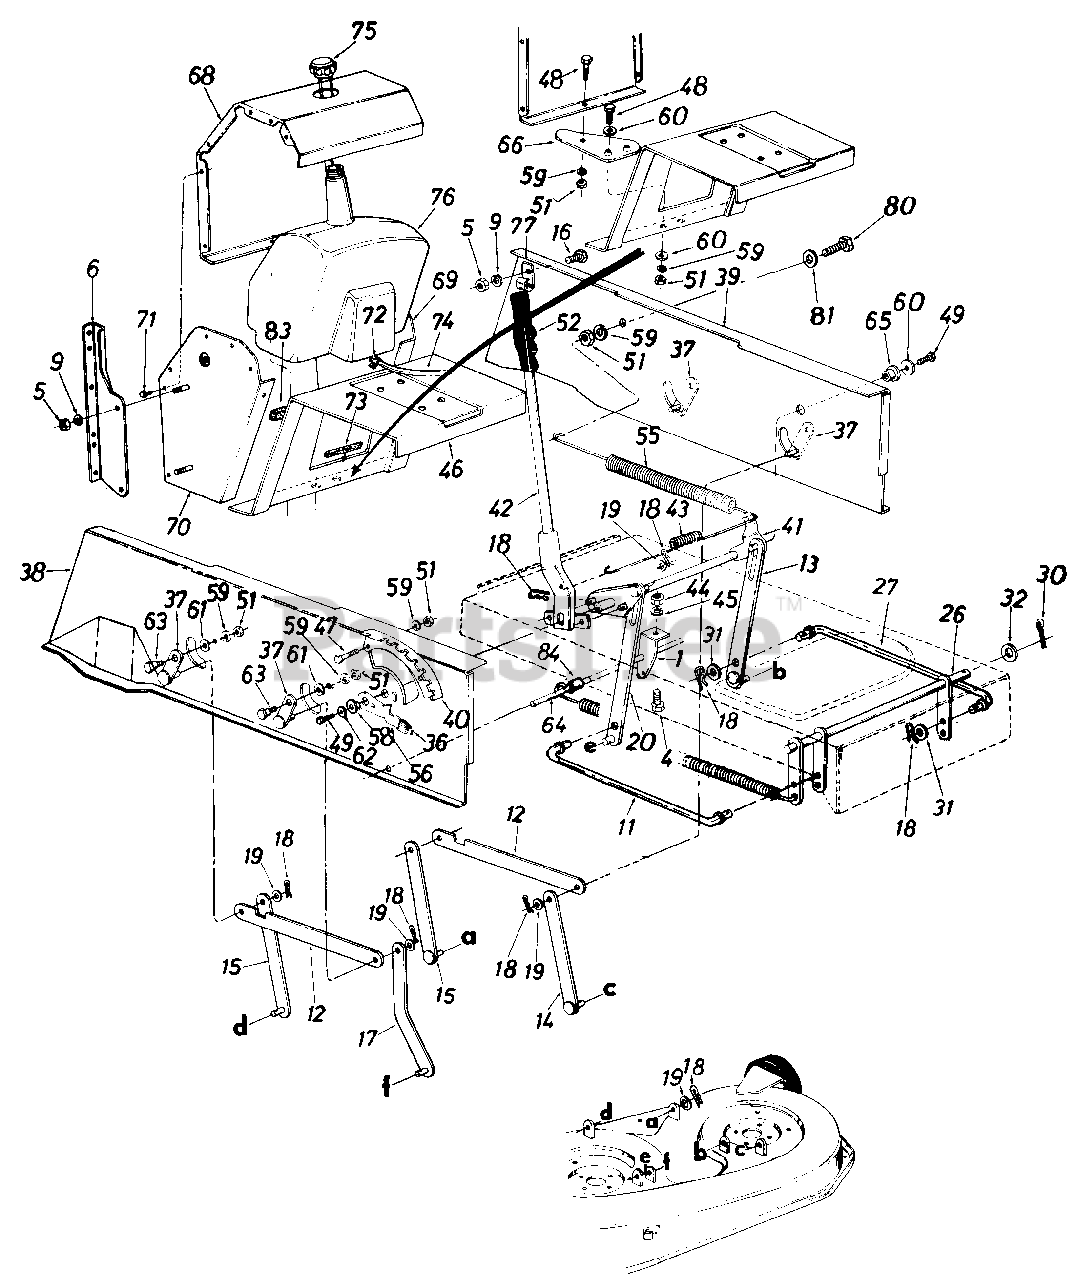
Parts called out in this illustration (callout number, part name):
1	Spring Hanger Bracket
4	Hex Bolt 1/4-20 x .62" Lg.
5	Hex Nut 5/16-18 Thd.
6	Mounting Bracket R.H.
9	L-Wash. 5/16" I.D.*
11	Stabilizer Rod
12	Connecting Rod 3/16 x 1 x 1 2.5
13	Deck Lift Link Ass'y.
14	Deck Hanger Link Ass'y. Rear L.H.
15	Deck Hanger Link Ass'y.
16	Hex Bolt 5/16-18 x .75" Lg.
17	Deck Hanger Link Ass'y.
18	Inter. Cotter Pin 1/2" Dia.
19	Fl-Wash. .531 I.D. x .93" O.D.
20	Deck Lift Link Ass'y.
26	Stabilizer Shaft Ass'y.
27	Stabilizer Rod
30	Cotter Pin 1/8" Dia. x 1.25" Lg.
31	Fl-Wash. .385" I.D. x .620" O.D.
32	Fl-Wash. .635" I.D. x 1.12" O.D.
36	Knob Height Adj.
37	Pivot Link Ass'y.
38	Side Panel Upper Frame R.H.
39	Side Panel Upper Frame L.H.
40	Index Brkt.
41	Lift Shaft Ass'y.
42	Lift Handle Brkt. Ass'y.
43	Ext. Spring .56" I.D. x 32 Coils
44	Hex Nut 1/4-20 Thd.
45	L-Wash. 1/4" I.D.
46	Hitch Plate
47	Hex Bolt 5/16-18 x .75" Lg.
48	Hex Bolt 5/16-18 x 1" Lg. (Grade 5)
49	Hex Wash. TT-Tap Scr. 5/16-18 x .62" Lg.
51	Hex Nut 5/16-18 Thd.
52	Grip
55	Ext. Spring .99" Dia. x 11.00" Lg.
56	Deck Lift Down Stop
58	Flange Brg. .630" I.D.
59	L-Wash. 5/16" I.D.
60	Fl-Wash. .344" I.D. x 1.125" O.D.
61	Fl-Wash. .344" I.D. x .62" O.D. x .063
62	Fl-Wash. .344" I.D. x 1.125" O.D.
63	Shld. Bolt .437" Dia. x .180
64	Running Board Rod
65	Flange Brg. .632" I.D.
68	Gas Tank Housing Main Panel
71	Truss. Mach. B-Tap Scr. #10 x .50" Lg.
72	Hose Clamp .406" Dia.
73	Trim Strip 5" Lg.
74	Gas Line 44" Lg.
75	Gas Tank Cap
80	Hex Bolt 5/16-18 x 1.50" Lg.
81	Fl-Wash. .344" I.D. x .875" O.D.
83	Foam Strip 318" x 1-1/8" x 1-l/2" Lg.
84	Spacer .523" I.D. x .640" O.D. x 1.95" Lg.
